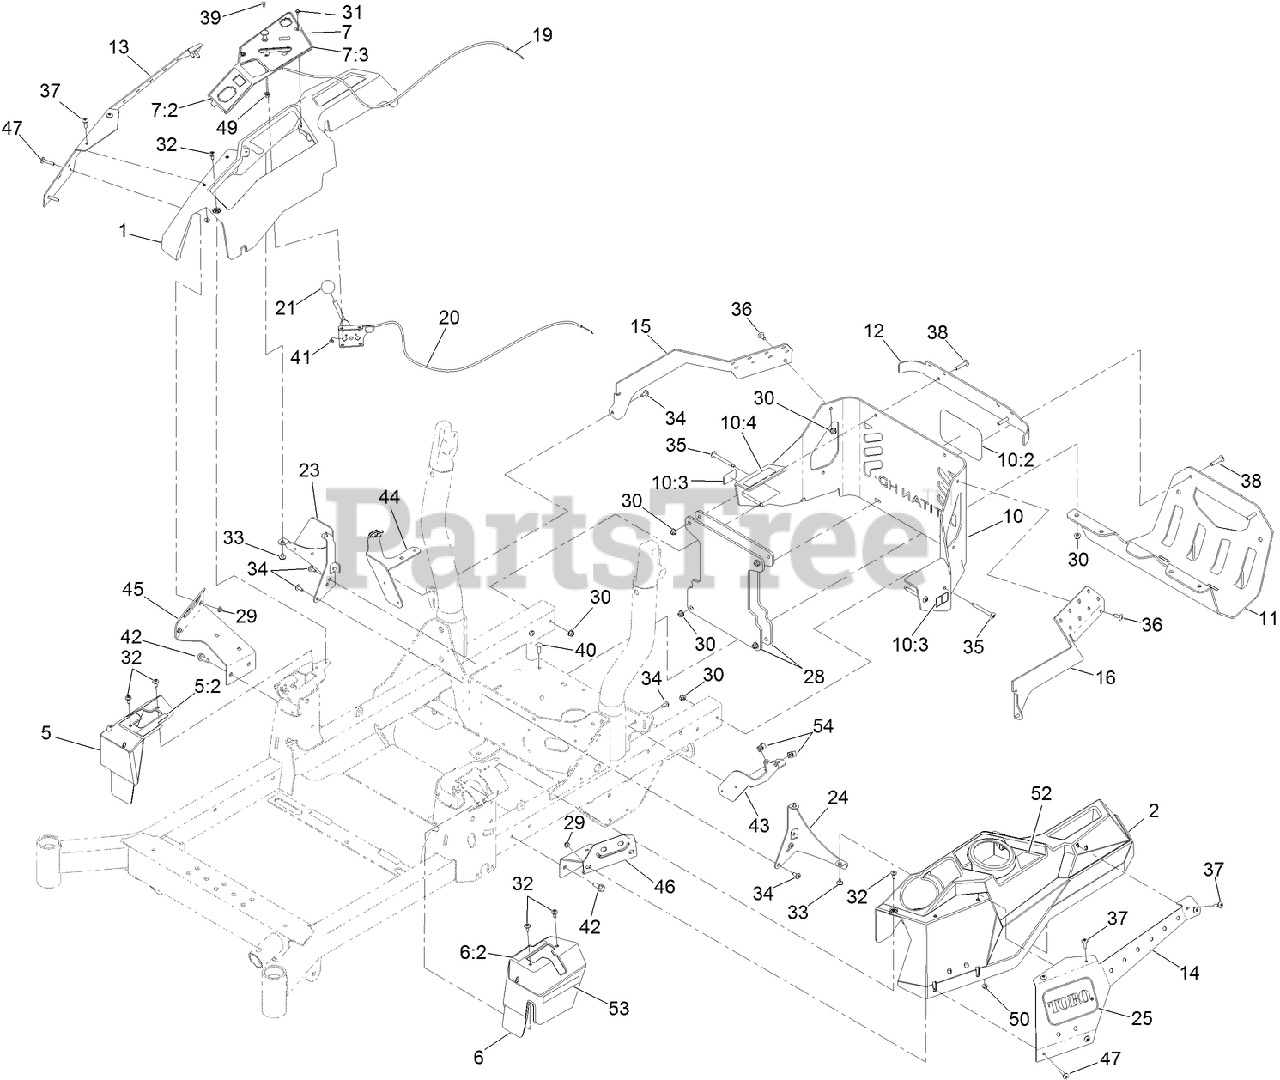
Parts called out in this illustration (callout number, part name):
1	CONSOLE-RH
2	CONSOLE-LH
5	COVER-CONTROL, MOTION (RH)
5:2	DECAL-CONTROL, MOTION (RH)
6	COVER-CONTROL, MOTION (LH)
6:2	DECAL-CONTROL, MOTION (LH)
7	CONTROL PANEL ASM
7:2	DECAL-PANEL, CONTROL
7:3	DECAL-PANEL, CONTROL
10	REAR GUARD ASM
10:2	DECAL
10:3	DECAL-WARNING
10:4	DECAL-ARRESTOR, SPARK
11	GUARD-MUFFLER
12	TRIM-UPPER, REAR
13	COVER-POD, RH
14	COVER-LH
15	BRACKET-GUARD, RH
16	BRACKET-GUARD, LH
19	CABLE-CONTROL, CHOKE
20	CABLE-CONTROL, THROTTLE
21	KNOB-BALL
23	SUPPORT-CONSOLE, RH
24	BRACKET-CONSOLE, LH
25	DECAL
28	WEIGHT-REAR
29	NUT-HF
30	NUT-HF, NI
31	SCREW-HWH
32	SCREW-SHOULDER
33	SCREW-TORX
34	SCREW-TORX
35	SCREW-TORX
36	SCREW-TORX
37	SCREW-TRUSS
38	SCREW-TORX
39	BOLT-CARR
40	SCREW-CARR
41	NUT-LOCK, NI
42	SCREW-FORMING, THREAD
43	BRACKET-SUPPORT, LEFT POD
44	BRACKET-SUPPORT, RIGHT POD
45	BRACKET-SUPPORT, POD (RH)
46	BRACKET-SUPPORT, POD (LH)
47	SCREW-TRUSS
49	NUT-HJ
50	NUT-KEPS
52	DECAL-FILL, FUEL
54	NUT-RETAINER
